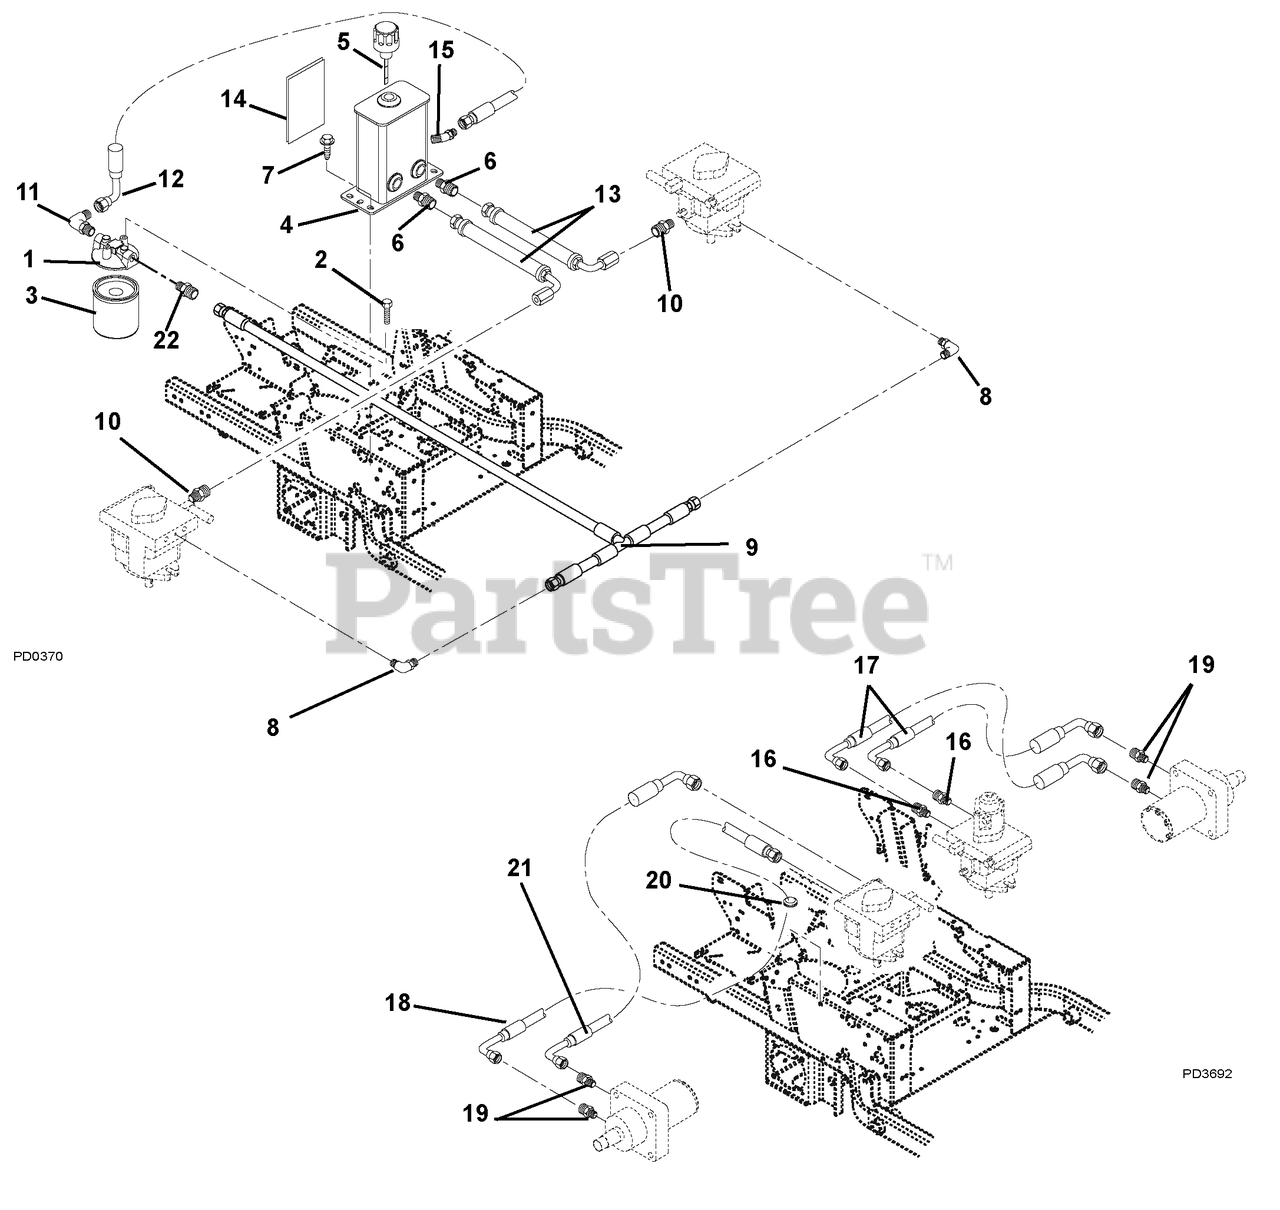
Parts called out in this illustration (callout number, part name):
1	HEAD, FILTER
2	BLT-HEX .25-20X.50 GR5 EPOXY
3	ELEMENT, OIL FILTER
4	WMT,FORMED HYD.TANK-3 PORT
5	BREATHER, DIPSTICK
6	FTG, HYD STR M8O-M4F
7	@SCR-TAP .38-16X.75 HWH TR YWZ
8	FITTING, HYD (6 C5OLO)
9	HOSE, HYD .50-9-0K F8FO-F8F9
10	FITTING, HYD (4-6 F5OLO)
11	FTG. HYD. 90 EL M8F-M8O
12	HOSE, HYD..50-11-OK F8F0-F8F9
13	HOSE, HYD .25-3-0K F4F0-F4F9
14	SHEILD, HEAT 5.50X4.50
15	ADPTR,FACE SEAL 8X8 1/2 O-RING
16	ADPTR,FACE SEAL 8X8 1/2 O-RING
17	HOSE,HYD .50-19-2K F08F9-F08F9
18	HOSE,HYD .50-20-2K F08FO-F08F9
19	FTG, HYD STR M10O-M8F
20	GROMMET 1.25ID X 1.5OD
21	HOSE,HYD .50-20-2K F08F0-F08F0
22	ADPTR,FACE SEAL 8X8 1/2 O-RING
